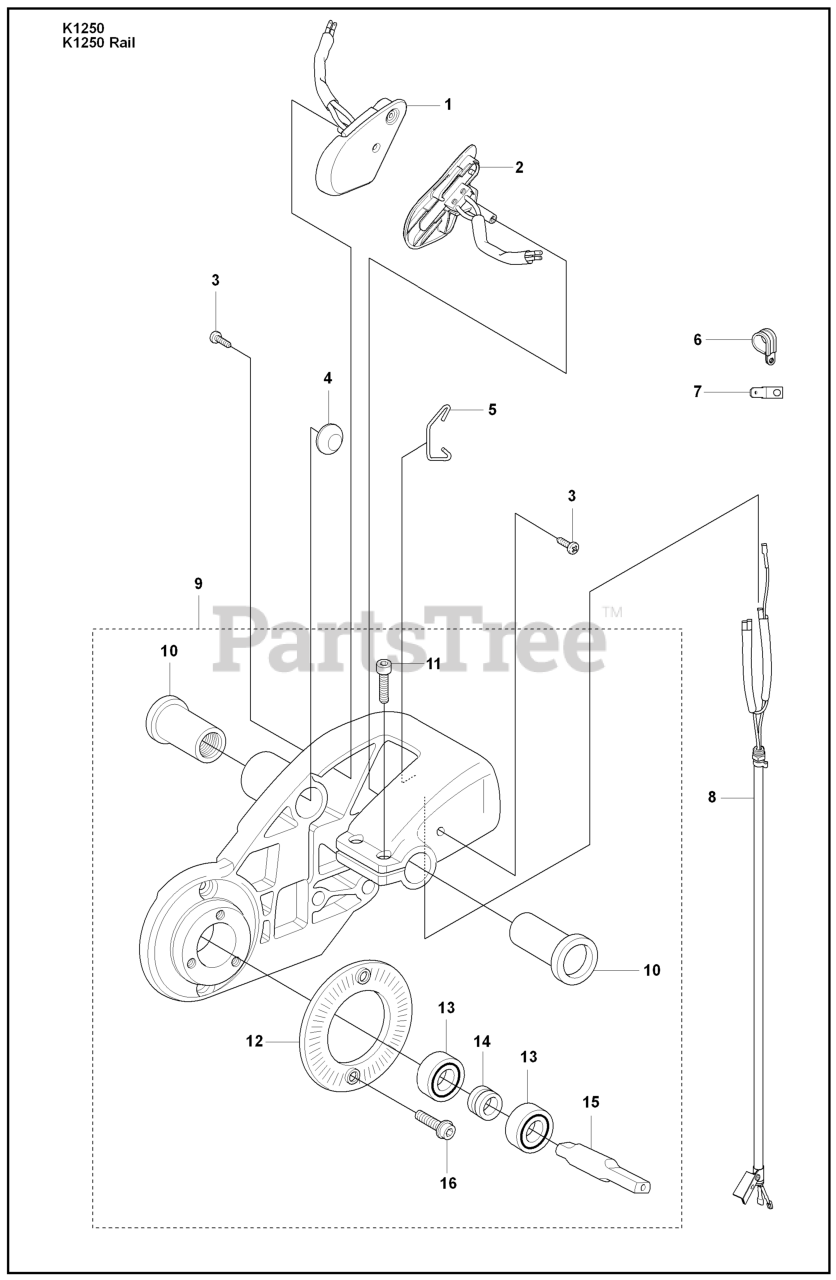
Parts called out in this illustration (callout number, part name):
1	STOP SWITCH RH
2	STOP SWITCH LH
8	CABLE ASSY
9	BEARING HOUSING
13	BALL BEARING
